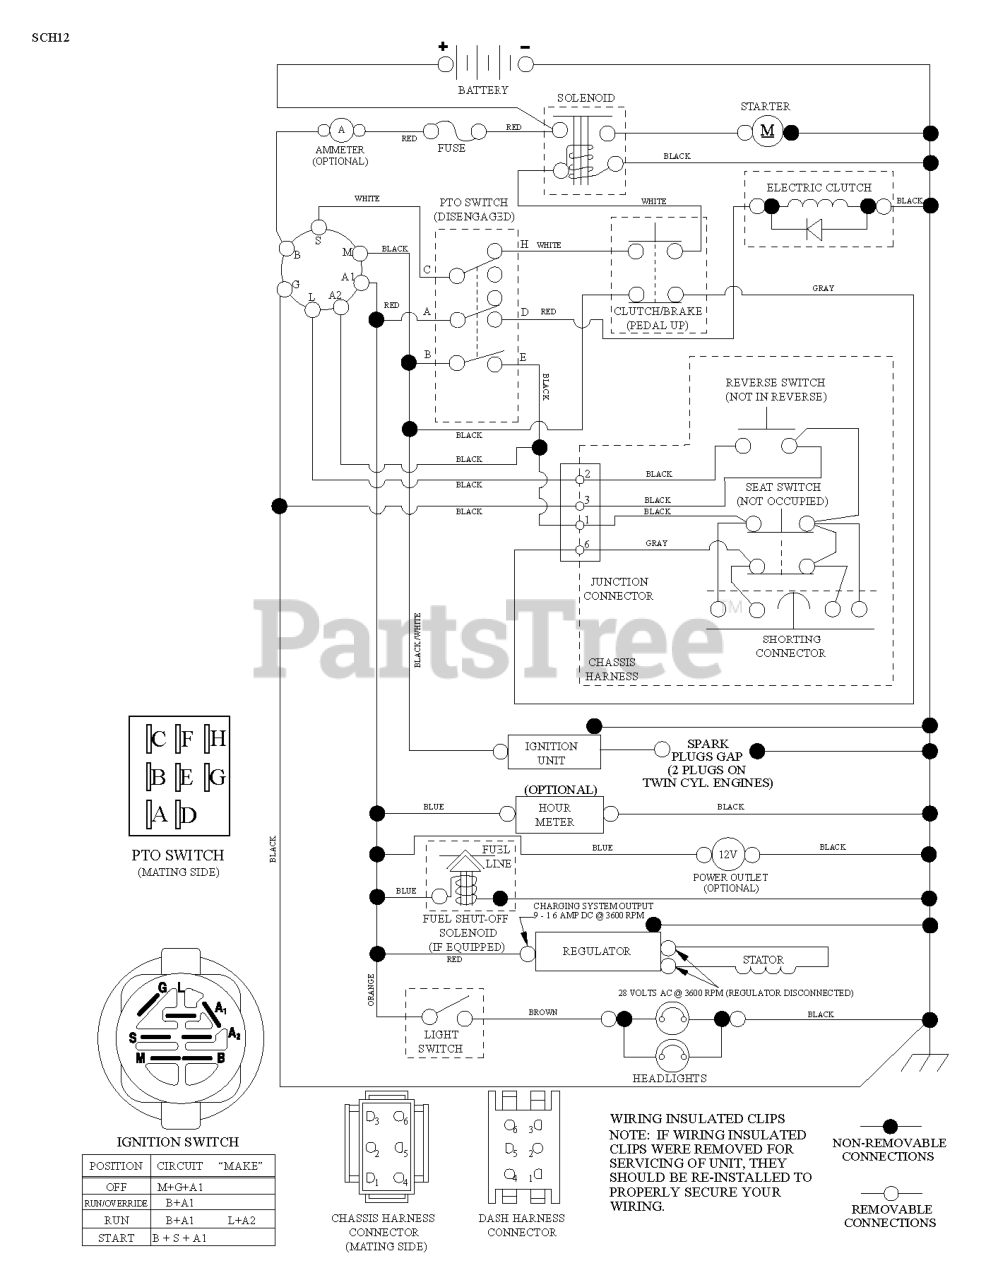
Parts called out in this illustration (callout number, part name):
2	VALVE STEM LT
3	TIRE HEAVY DUTY
4	TUBE.5.3/4.5/6
5	RIM ASM 6" FRONT SILVER
6	FITTING LT
7	BEARING T
8	RIM ASM 8" REAR SILVER
9	TIRE.TS.20X10-8
10	TUBE
11	CAP, AXLE BLK
